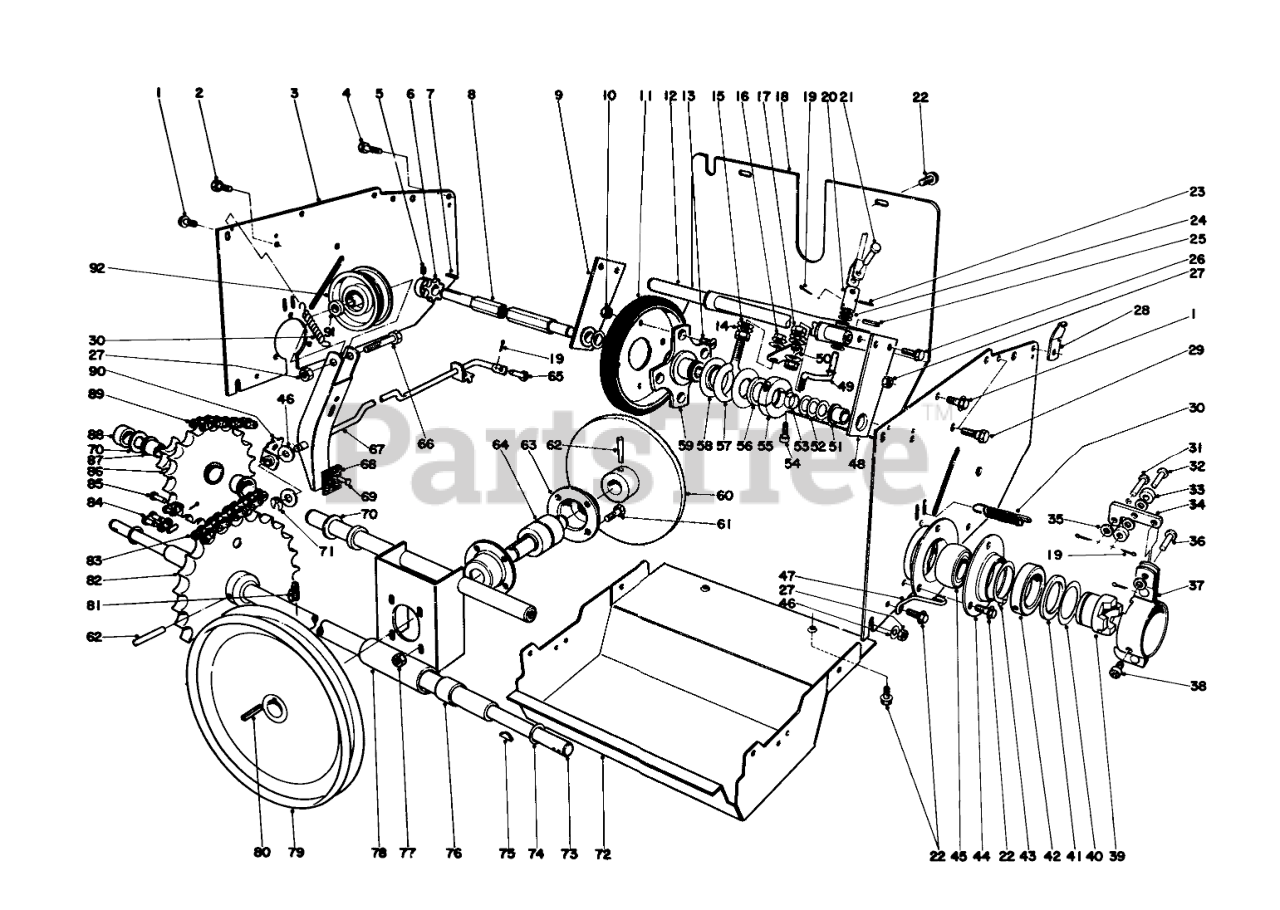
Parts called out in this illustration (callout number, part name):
1	SCREW-HHF
2	SCREW-HWH,THD ROLL
3	Side Plate Drive
4	SCREW-HH, TAP
5	SCREW-HSH
6	SPROCKET
8	FRICTION WHEEL SHAFT
9	Hex Shaft Mount Right (Incl. Ref. #51)
10	Nut
11	Disc
12	Bracket Dead Shaft
13	5/16-18X5/8 FLT HD MS
14	Washer
15	WASHER-SPRING
16	NUT-LOCK, FLANGE
17	Nut
18	REAR COVER R
19	PIN-COTTER
20	U JOINT TUBE
21	CLEVIS PIN
22	SCREW-HWH
23	PIN-SPRING
24	Spacer
25	PIN-ROLL
26	SCREW-HWHTF
27	NUT-HEX
28	HANDLE MTG BRKT
29	SHOULDER SCREW
30	EXTENSION SPRING
31	PIN-CLEVIS
32	PIN-CLEVIS
33	CLUTCH ROLLER
34	CLUTCH CAM ARM
35	WASHER-FLAT
36	PIN-CLEVIS
37	CLUTCH MT BRKT ASM
38	Hex Socket Capscrew
39	Clutch Wheel
40	THRUST WASHER
41	THRUST BEARING
42	CLUTCH MOUNT COLLAR
43	RING-RETAINING, EXTERNAL
44	BEARING FLANGE
45	BEARING
46	WASHER-FLAT
47	Clutch Retainer
48	Hex Shaft Mount Left (Incl. Ref. #51)
49	CONNECTION ROD
50	SHIFT ROD PIVOT
51	BUSHING
52	WASHER-FLAT
53	SPLIT SPACER
54	SCREW-HSH
55	Collar
56	WASHER-THRUST
57	SLIDER RING COLLAR
58	SLIDER RING
59	TRACTION DISC HUB
60	FRICTION PLT WA
61	SCREW-HH
62	PIN-GROOVED
63	HOUSING BEARING
64	Friction Plate Shaft
65	PIN-CLEVIS
66	SCREW-HH
67	Auger Idler & Brake (Incl. Ref. #68 & 69)
68	BRAKE PAD
69	.185 DIA X .375 RT +
70	WASHER-THRUST
71	Klip Ring
72	LOWER SHIELD R
73	Axle Shaft
74	WASHER
75	1/4X1-1/16 HI-PRO KEY
76	BUSHING
77	NUT-KEPS
78	Bulkhead
79	Pulley
81	Set Screw
82	Sprocket
83	Chain Lower
84	LINK-CONNECTING
85	1/4 OFFSET LINK
86	Sprocket (Incl. Ref. #87)
87	3/4ID X 3/4LG BSHG
88	Spacer
89	1/4 X 42 CHAIN W/LINK
90	Bracket-Clutch
91	Spacer
92	Idler Pulley
